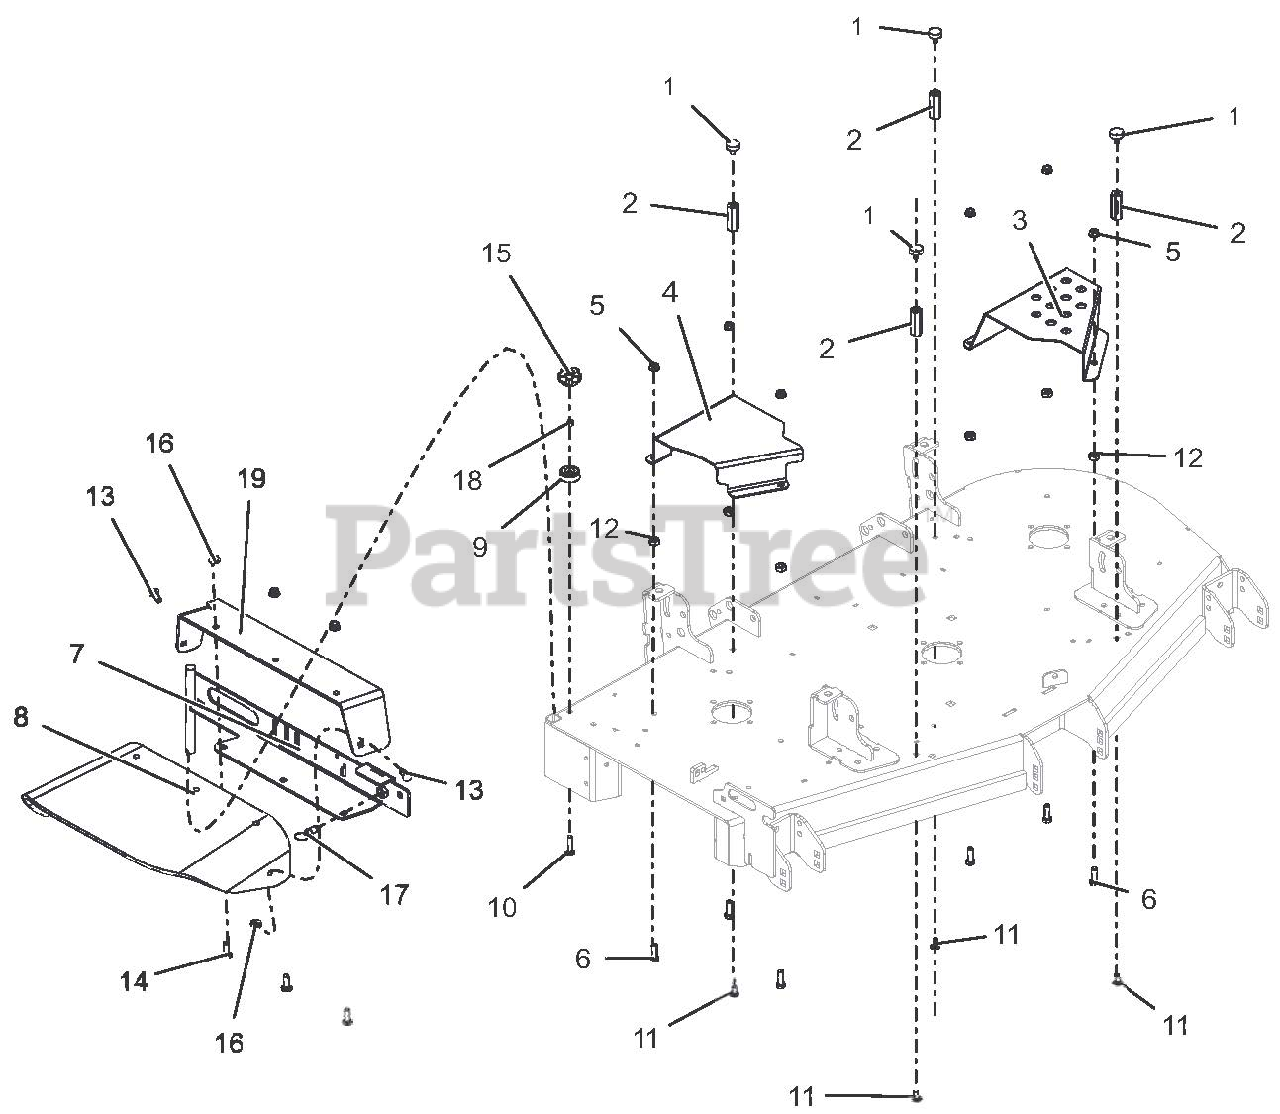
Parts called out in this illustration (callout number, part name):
1	BUMPER, RUBBER
2	NUT, .31-18 X 2.25 LG COUPLING
3	GUARD, 44-52" LH DECK BELT-BLACK
4	GUARD, 48"-52" RH DECK BELT-BLACK
5	@NUT-SPNLK-FLG .375-16 YWZC
6	BLT-HEX .38-16X1.25 GR5 YWZC
7	WLDMT, 52"-60" DISCH CHUTE MTG-RED
8	CHUTE, RUBBER DISCHARGE
9	BUMPER, RECESSED 1.50 X .63 W/.31 HOLE
10	BLT-RDHDSQNK .31-18X1.50 G5 YWZC
11	BLT, RDHDSQNK .31-18X.75 LOCTITE
12	NUT-HEAVY HEX .38-16 YWZC
13	BLT-RDHDSQNK .38-16X1.00 G5 YWZC
14	BLT-RDHDSQNK .38-16X1.25 G5 YWZC
15	KNOB, CLAMPING
16	NUT-LK-NYL-FLG .38-16 YWZC
17	PULL PIN,.50-13THDX.310 PLNGR
18	NUT-LK-CTR .31-18 YWZC
19	DISCHARGE CHUTE SUPPORT W/SAFETY DECAL-RED
